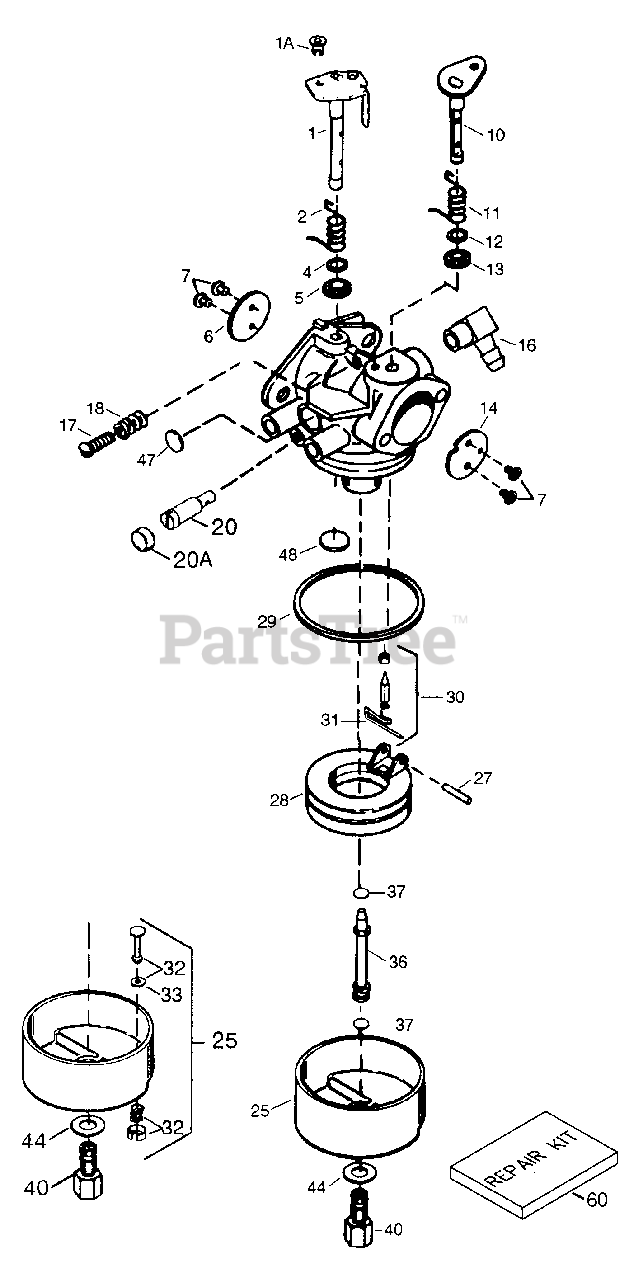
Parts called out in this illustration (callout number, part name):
1	Throttle Shaft & Lever Assembly
1A	Throttle Link Bushing
2	Throttle Return Spring
4	* Dust Seal Washer
5	* Dust Seal (Throttle)
6	Throttle Shutter
7	* Shutter Screw
10	Choke Shaft & Lever Assembly
11	Choke Return Spring
12	* Dust Seal Washer
13	* Dust Seal (Choke)
14	Choke Shutter
15	Choke Positioning Spring
16	Fuel Fitting
17	Throttle Crack Screw/Idle Speed Screw
18	Tension Spring
20	Idle Restrictor Screw
20A	Idle Restrictor Screw Cap
25	Float Bowl
27	* Float Shaft
28	Float (Plastic)
29	* Float Bowl "O" Ring
30	* Inlet Needle, Seat, & Clip (Incl. 31)
31	Spring Clip
36	Main Nozzle Tube
37	* Main Nozzle Tube "O" Ring
40	High Speed Bowl Nut
44	* Bowl Nut Washer
47	* Welch Plug, Idle Mixture Well
48	* Welch Plug, Atmospheric Vent
60	Repair Kit Incl. items marked PK inn otes
